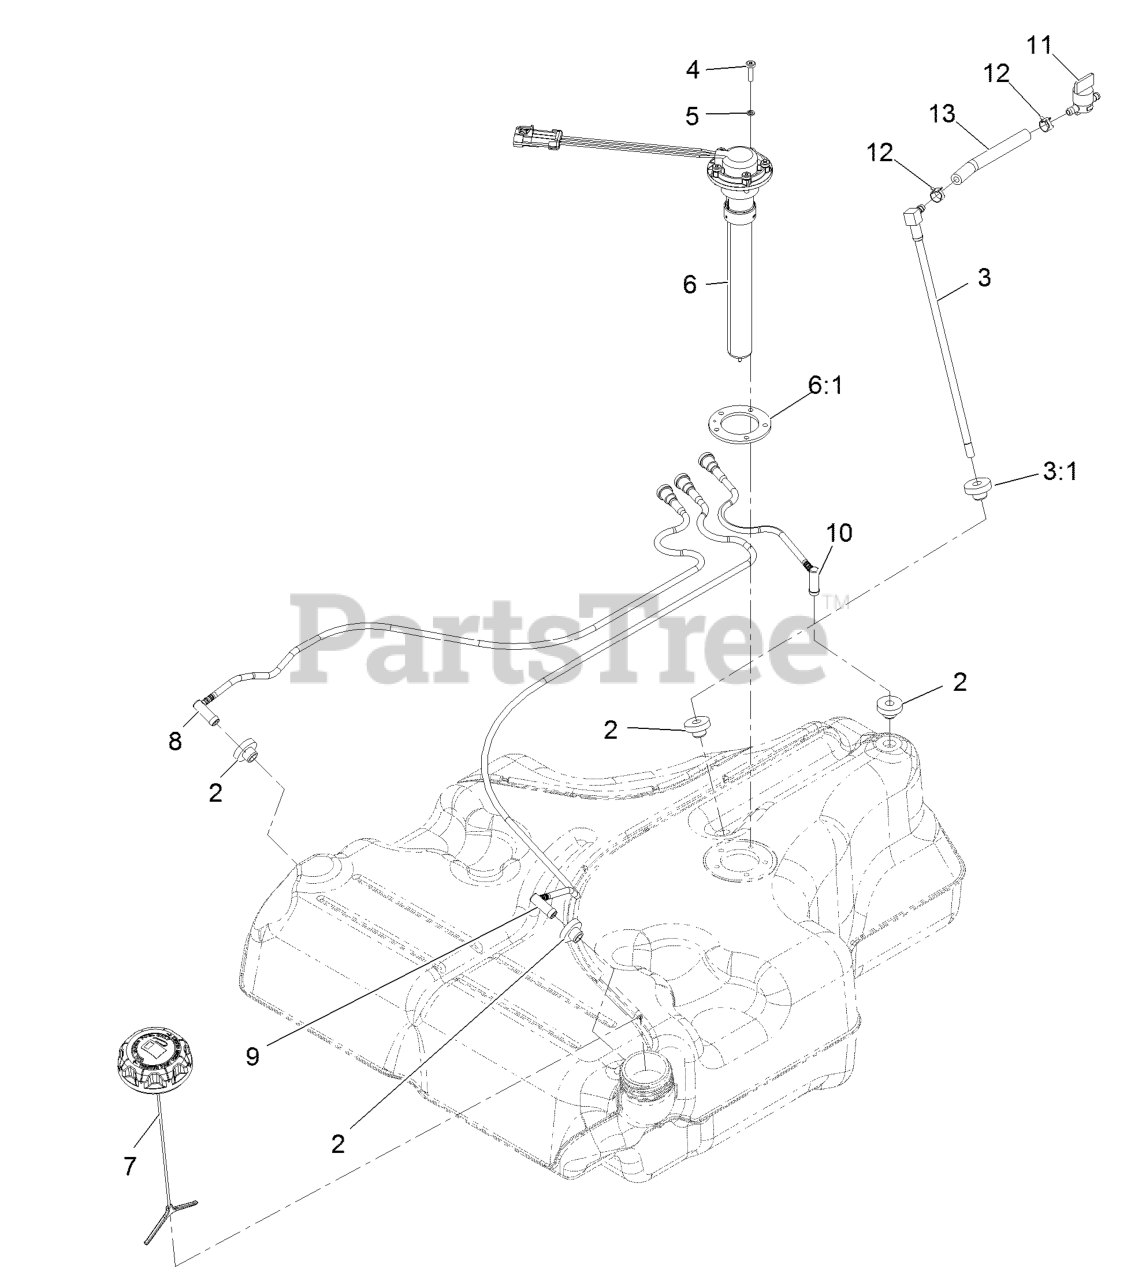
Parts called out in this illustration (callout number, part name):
2	BUSHING
3	FUEL LINE KIT (WITH GROMMET)
3:1	BUSHING
4	SCREW-PAN
5	WASHER-LOCK
6:1	GASKET-SENDER, FUEL
7	CAP-FUEL, RATCHETING
8	RH VENT LINE KIT (WITH GROMMET)
9	LH VENT LINE KIT (WITH GROMMET)
10	REAR VENT LINE KIT (WITH GROMMET)
11	VALVE-FUEL
12	CLAMP-HOSE
13	HOSE-FUEL
